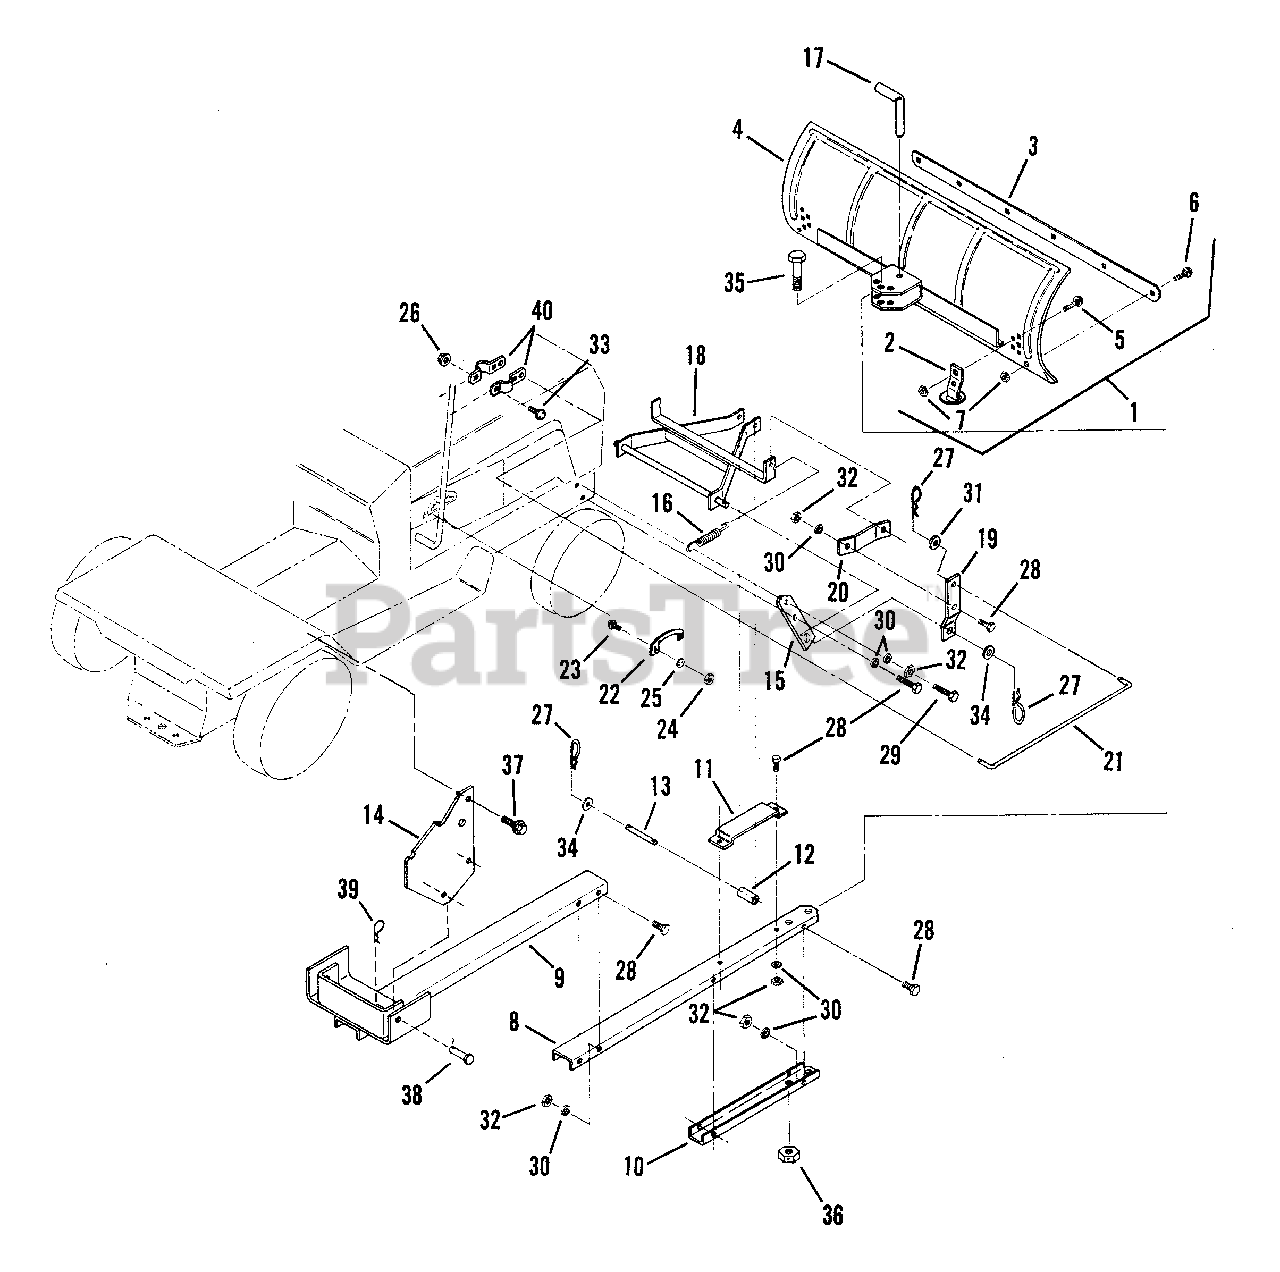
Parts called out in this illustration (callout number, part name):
1	ASSEMBLY, Blade 42"
2	SLIDE STRUCTURE
3	SCRAPER
5	CARRIAGE BOLT, 3/8Cx1" Round Head
6	CARRIAGE BOLT 3/8Cx3/4 Short Neck
7	NUT, 3/8-16 Hex Center Lock
8	BEAM, Front
9	WELDMENT, Hitch
10	PLATE, Front Hitch
11	BRACKET, Lift
12	ROLLER, Lift
13	PIN, Lift Roller
14	BRACKET
15	PLATE, Side Support
16	SPRING, Lift Assist
17	PIN, Latch
18	STRUCTURE, Lift Yoke
19	ARM, Lift
21	ROD, Operating
22	PLATE, Quadrant Lockout
23	CARRIAGE BOLT, 1/4Cx5/8 Flat Head
24	NUT, 1/4C Hex
25	LOCKWASHER, 1/4 Internal Tooth
26	NUT, 1/4-20 Hex Flange Lock
27	PIN, Hair Cotter
28	SCREW, 3/8Cx1 Hex Head Cap
29	SCREW, 3/8Cx1 1/2 Hex Head Cap
30	WASHER 3/8 Split Lock
31	WASHER, 3/8" Flat
32	NUT, 3/8C Hex
33	BOLT, 1/4-20x1/2" Short Neck Cariage
34	WASHER, 1/2 Flat
35	SCREW, 1/2Fx2 3/4 Hex Head Cap
36	NUT, 1/2F Hex Lock
37	BOLT, 5/16-18x1" Hex Flange Lock
38	PIN, 1/2x1-3/8 Clevis
39	PIN, Hair
40	TAB, Lift Lever
